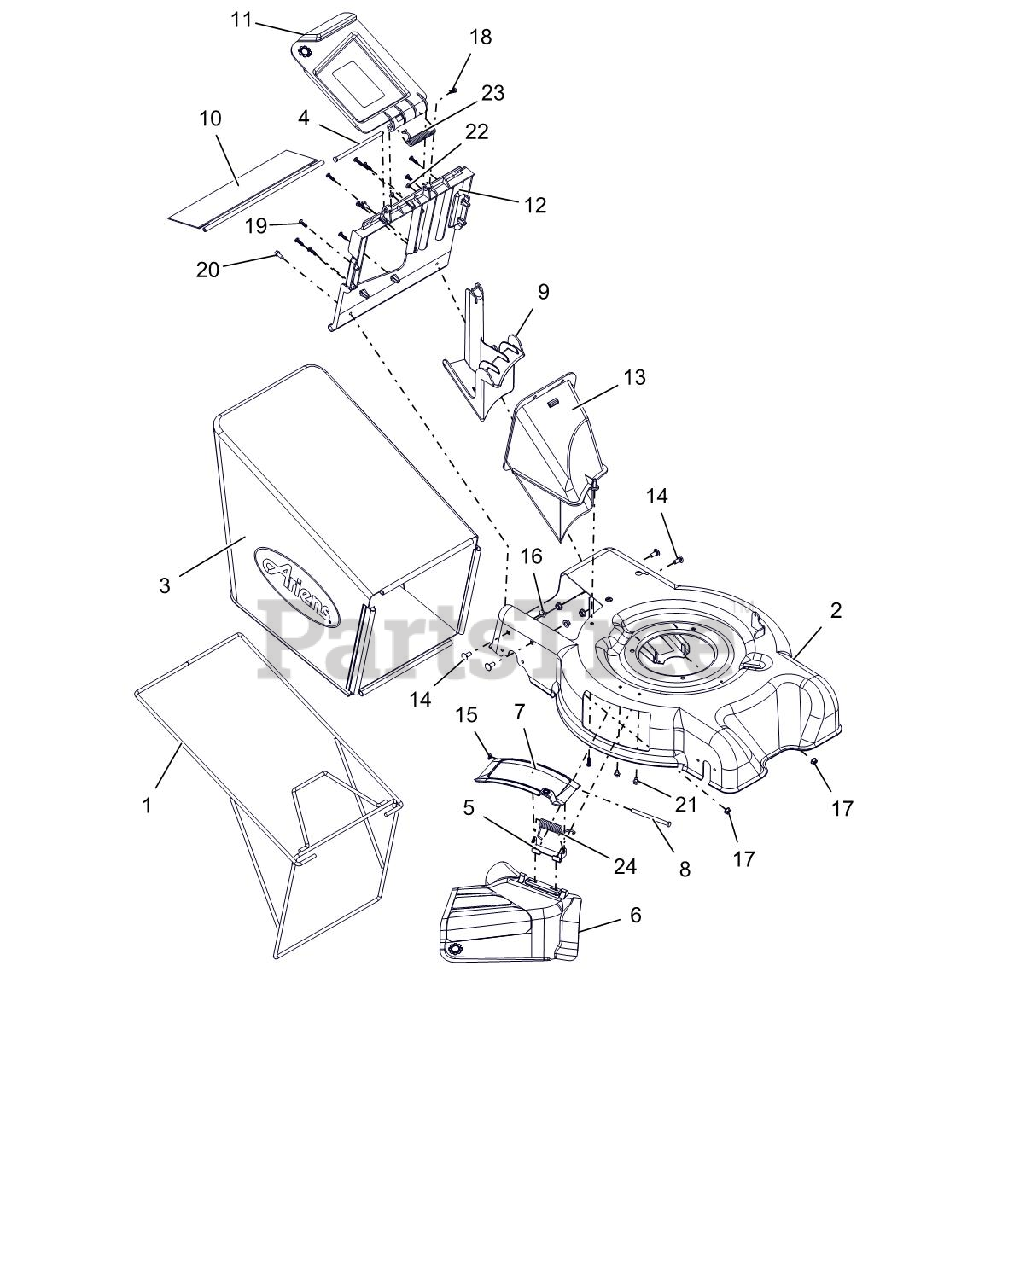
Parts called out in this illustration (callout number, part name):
1	FRAME, BAGGER
2	DECK, RAZOR W/ SAFETY DECALS
3	BAGGER, ARIENS LM
4	PIN, 5/16 X 5.80"
5	BRKT, HINGE LM
6	CHUTE, SIDE DISCHARGE - LM
7	COVER, SIDE DISCHARGE - LM
8	PIN, HINGE
9	PLUG, MULCH
10	GUARD, REAR DECK
11	REAR DOOR W/ SAFETY DECAL
12	HANGER, REAR BAG
13	CHUTE, REAR DISCHARGE LM
14	@BLT-RDHDSQNK .31-18X.75 G5YZ
15	NUT-PUSH .312
16	@NUT-LK-TOP-FLG .31-18 YWZC
17	@NUT-LK-TOP-FLG .25-20 YWZC
18	PIN-HAIR INT .08X.18X1.18 YWZC
19	SCR-TAP 12-14X.75PLSTITE @BLZC
20	@SCR-TAP .25-20X.62 HWH TR YWZ
21	@SCR-TAP .25-20X.37 HWH YWZ TR
22	PLUG,5/16 HOLE,.125 MATL PLSTC
23	SG-TORS .120X.68X3.09
24	SPRING, SIDE DISCHARGE DOOR
